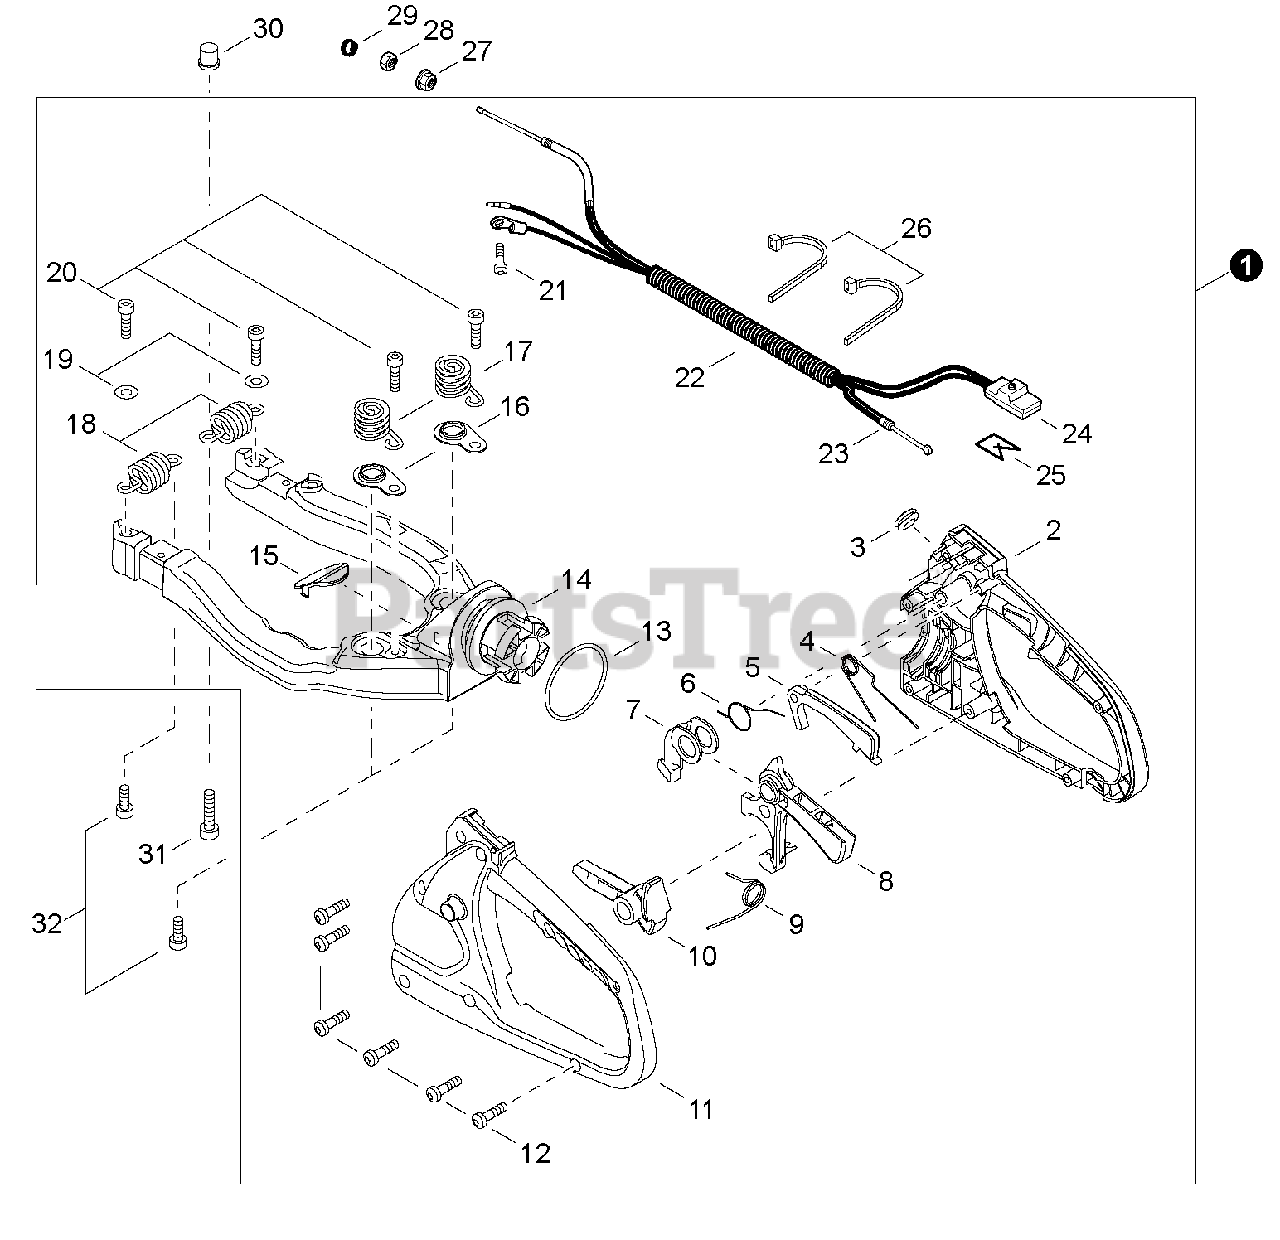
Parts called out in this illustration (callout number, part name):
1	HANDLE ASSY - REAR
2	HANDLE, REAR - RIGHT
3	GROMMET
4	SPRING, LOCKOUT
5	LEVER, TRIGGER LOCKOUT
6	SPRING, TRIGGER
7	LEVER, THROTTLE
8	TRIGGER, THROTTLE
9	SPRING, TRIGGER
10	LEVER, HANDLE RELEASE
11	HANDLE, REAR - LEFT
12	SCREW - 4X16 -- TAPPING
14	FRAME
15	COVER, HANDLE
16	HOLDER, SPRING
20	SCREW - 6X20
21	SCREW - 4X8
22	TUBE, PROTECTIVE
23	CABLE, THROTTLE
24	SWITCH, IGNITION
26	TIE, CABLE
27	NUT - 6 -- FLANGE
31	SCREW - 6X25
32	SCREW - 6
